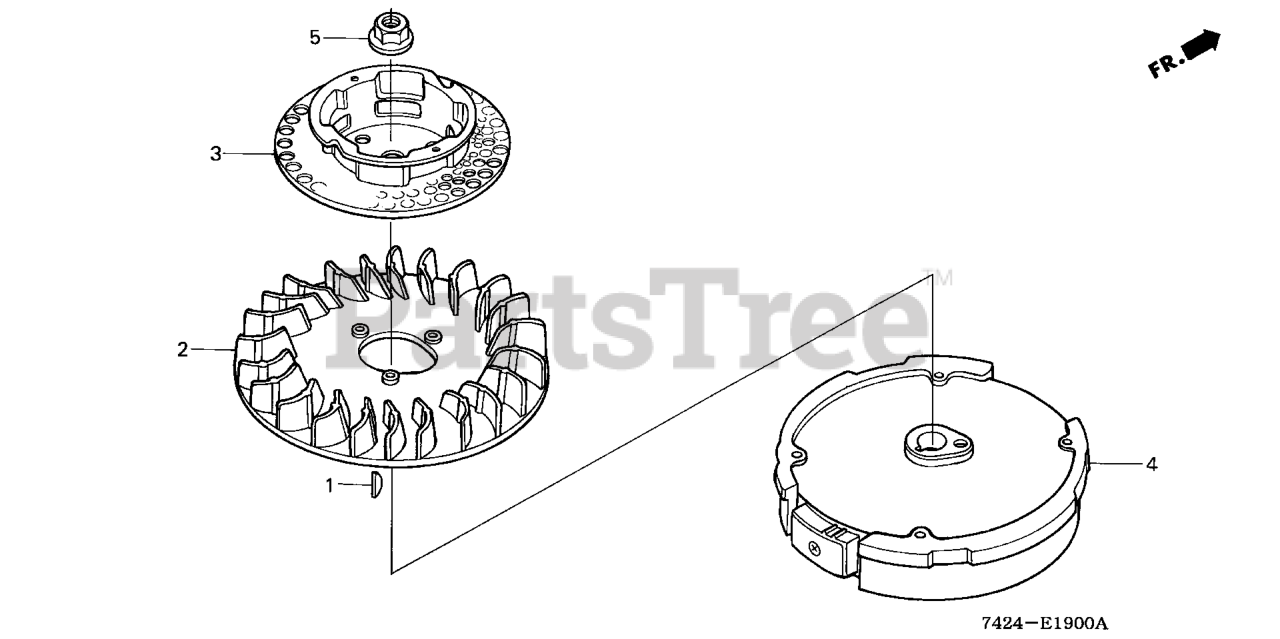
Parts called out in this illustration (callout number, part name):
1	KEY, SPECIAL WOODRUFF (25X18)
2	FAN, COOLING
3	PULLEY, STARTER
4	FLYWHEEL
5	NUT, SPECIAL (14MM)
